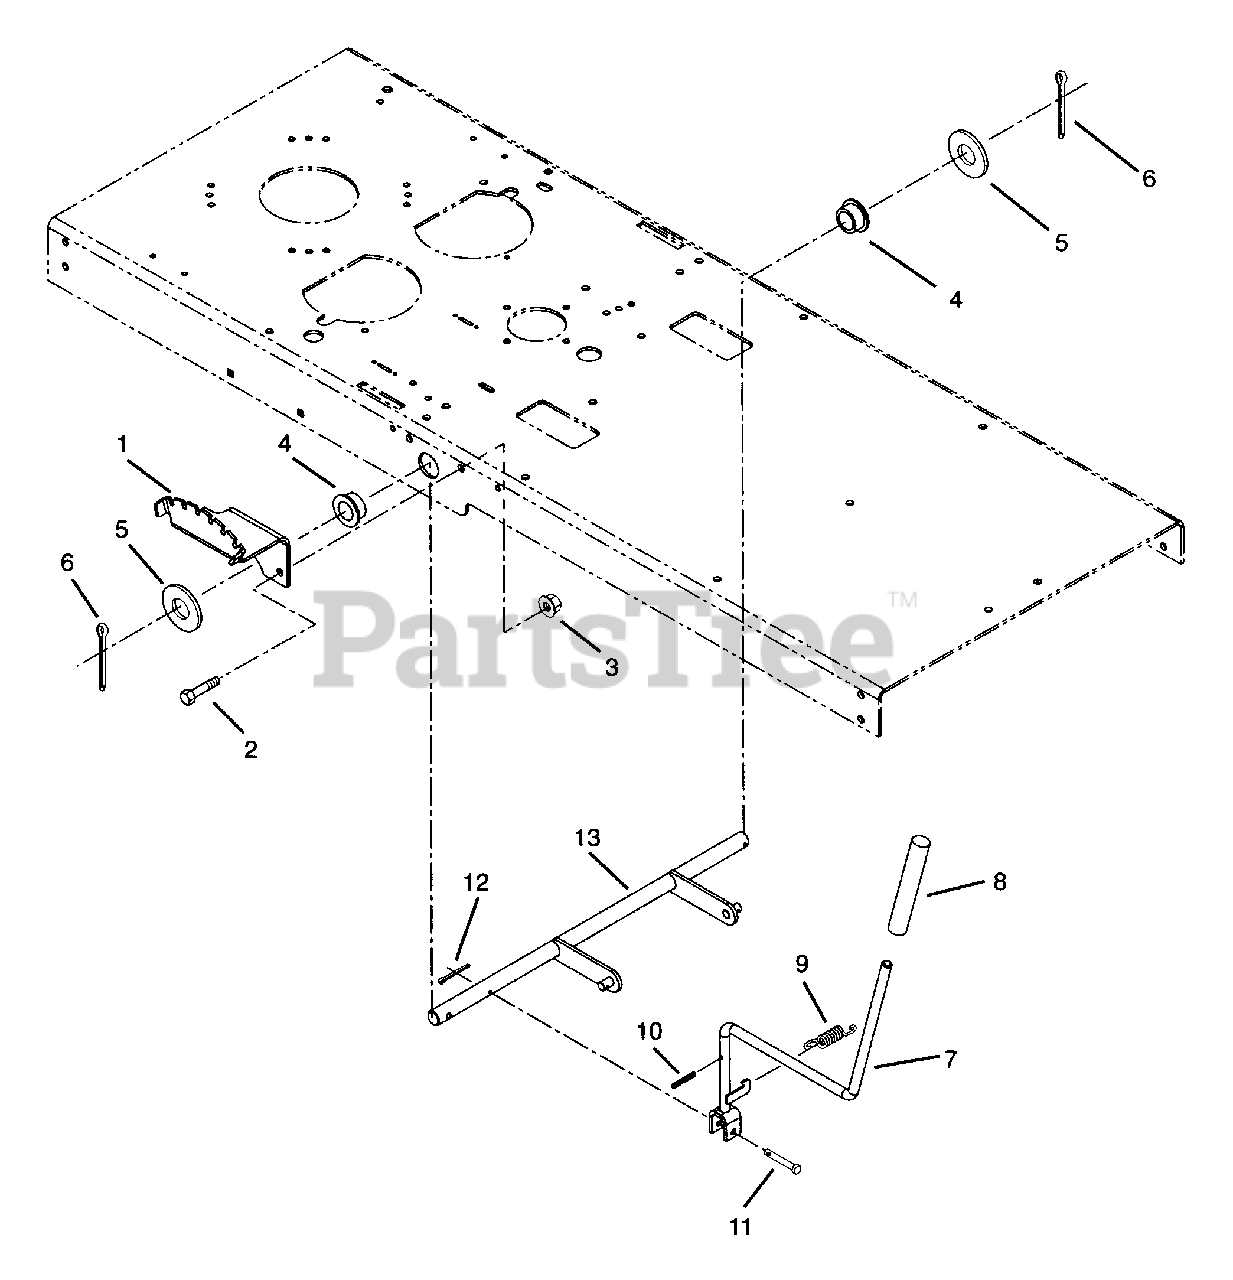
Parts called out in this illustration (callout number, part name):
1	DETENT BRACKET
2	BLT-HEX .38-16X1.00 PL GR5
3	NUT-LK-NYL .375-16 PL
4	BSHG-FLG1.020X1.385X.75X1.75NY
5	WSHR-FL-STL 1.062X2.000X.134
6	PIN-COTR .188X1.50
7	LIFT WELDMENT
9	SG-TENS .092X.69X1.75 WLD 54
10	PIN-ROLL .250X1.00
11	PIN-CLEV .370X1.75
12	PIN-COTR .12X1.0 PL
13	LIFT SHAFT WELDMENT
